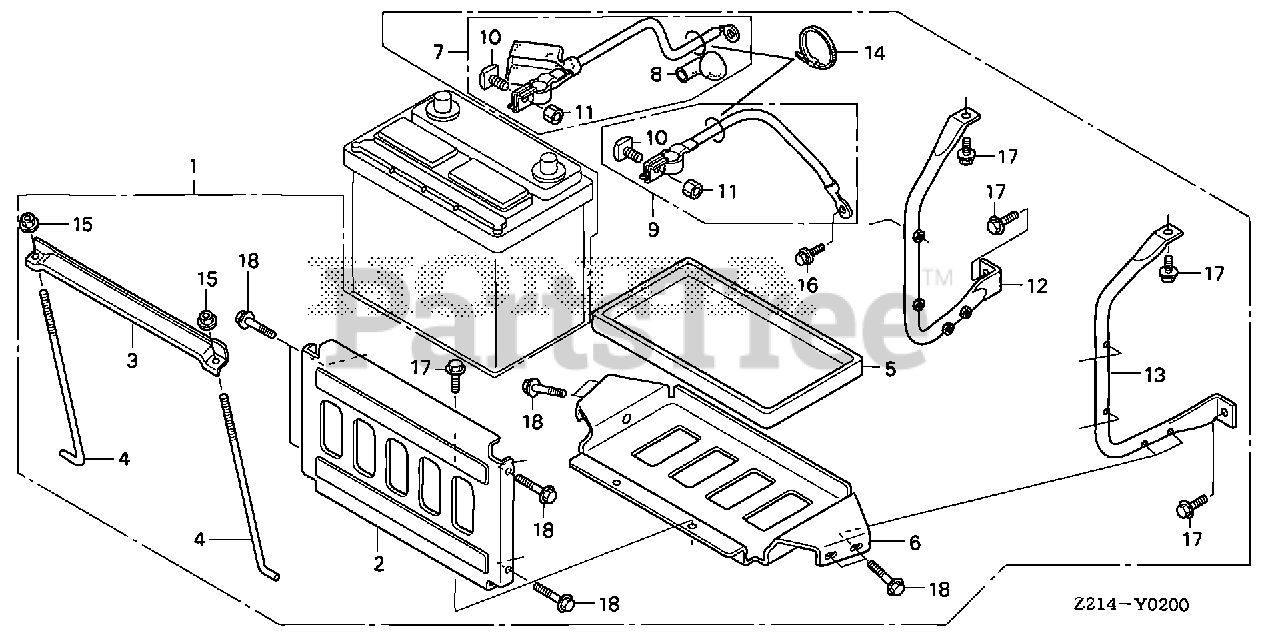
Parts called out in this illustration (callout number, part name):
1	TRAY KIT, BATTERY *NH105* (MAT BLACK)
2	PLATE, BATTERY GUARD *NH105* (MAT BLACK)
3	PLATE, BATTERY SETTING
4	BOLT, BATTERY SETTING
5	BOX ASSY., BATTERY
6	BASE, BATTERY TRAY *NH105* (MAT BLACK)
7	CABLE ASSY., STARTING
8	COVER, STARTER MOTOR TERMINAL
9	CABLE ASSY., GROUND
10	BOLT, BATTERY TERMINAL
11	NUT, BATTERY TERMINAL
12	GUARD, FR. BATTERY *NH105* (MAT BLACK)
13	GUARD, RR. BATTERY *NH105* (MAT BLACK)
14	BAND, WIRE (95MM)
15	NUT, FLANGE (6MM)
16	BOLT, FLANGE (6X12)
17	BOLT, FLANGE (8X12)
18	BOLT, FLANGE (8X40)
NI	BATTERY (GROUP 51R PE) (NOT AVAILABLE) (MSDS)
